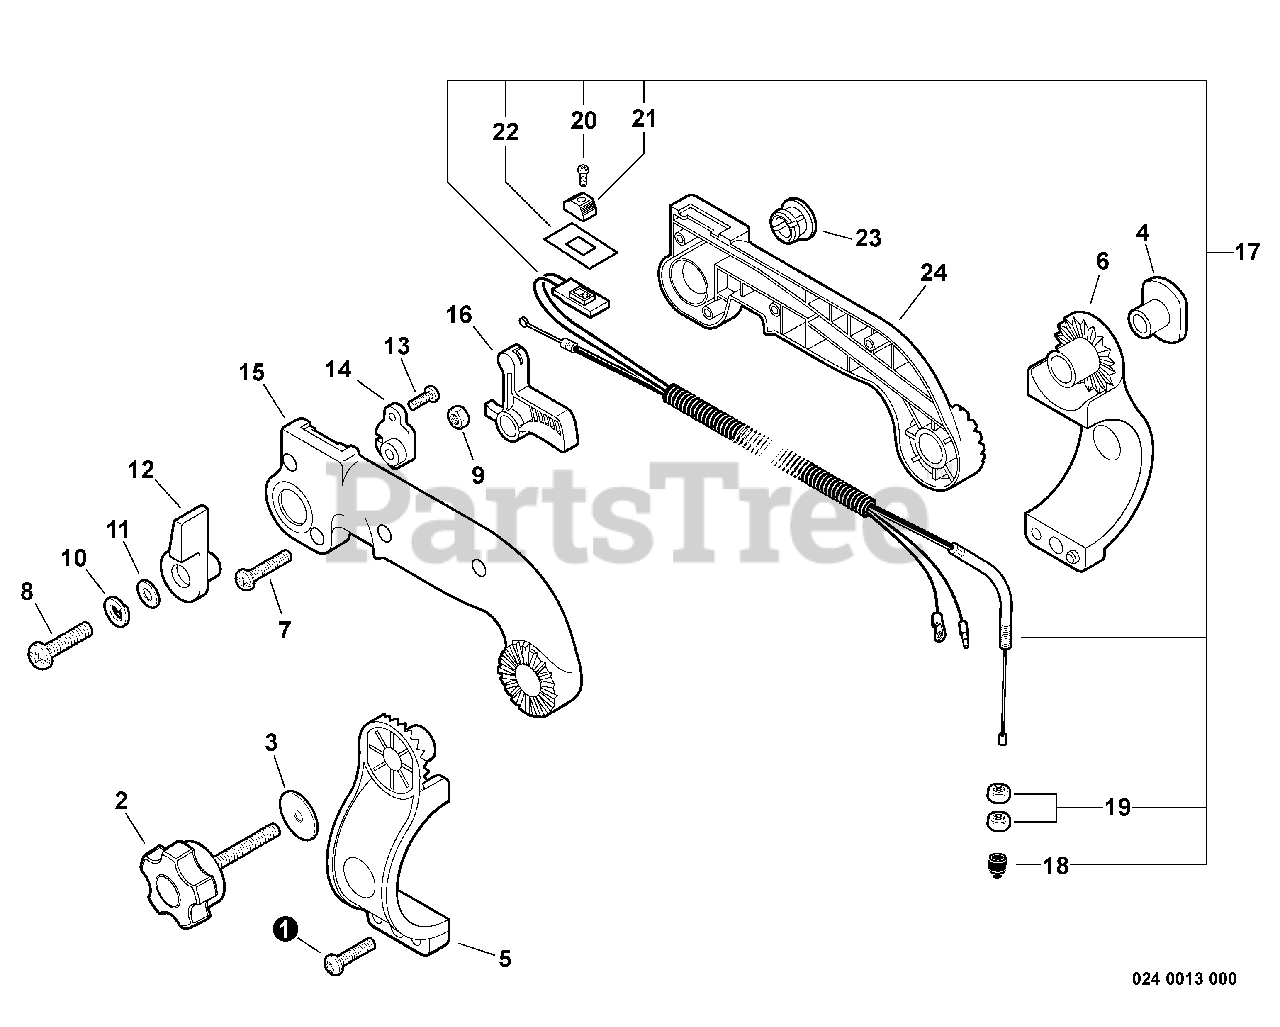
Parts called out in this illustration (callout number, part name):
1	SCREW TAPPING 5×20
2	KNOB, SCREW
5	BRACKET, HANDLE - LEFT
6	BRACKET, HANDLE - RIGHT
7	SCREW 4×22
8	SCREW 6×20
9	NUT, HEX M6
10	WASHER, SPRING 6
11	WASHER 6.5×13×1
12	CONTROL, THROTTLE
13	SCREW 4×10
14	BRACKET, THROTTLE
15	CONTROL HANDLE - LEFT
16	TRIGGER, THROTTLE
17	CABLE ASSY, CONTROL
18	CAP, DUST
19	NUT 6 MM
20	SCREW 3×10
21	KNOB, SWITCH - ORANGE
22	LABEL, SWITCH
24	CONTROL HANDLE - RIGHT
